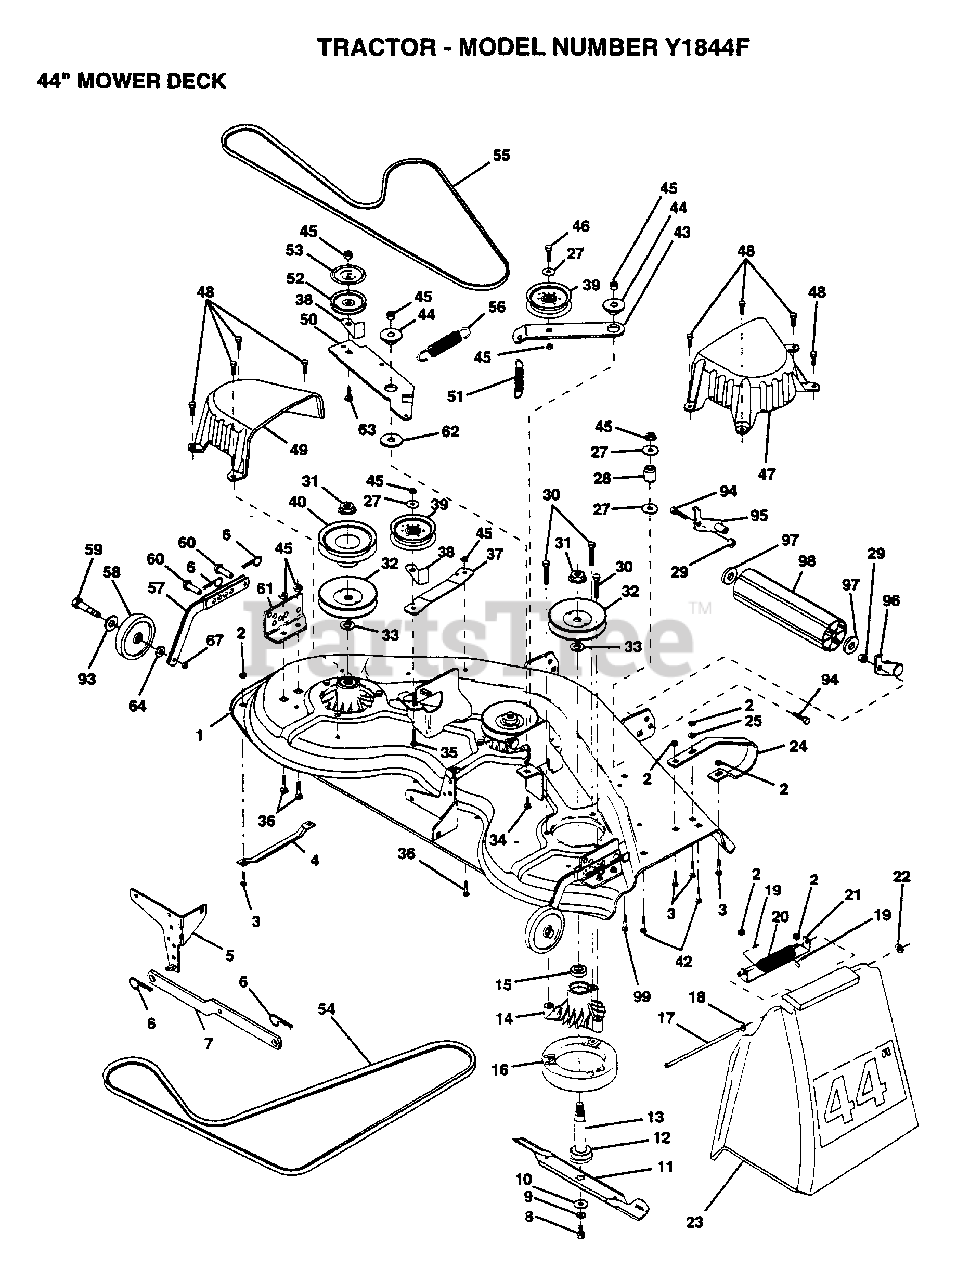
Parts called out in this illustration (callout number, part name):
1	"DECK ASM WELD44"""
4	RUNNER-LH M
5	BRKT.ASM.SW.44/50
8	BLADE BOLT
10	WASHER.HARD.BLADE
11	"BLADE.44"" HIPERF"
12	BEARING.BALL
13	SHAFT.ASM.W/BRNG
14	HOUSING.MAND.44.V
15	BEARING
16	STRIPPER RND MWR
17	ROD-HINGE T
18	WASHER
19	CAP-SLEEVE LT
20	SPRING TORSION
21	BRKT DEFLECTOR
22	NUT PUSH M
23	DEFLECTOR SHIELD
24	RUNNER.RH
24	WASHER M
27	WASHER
29	NUT
33	WASHER
34	BOLT.3/8-14X1.25
35	BOLT
36	BOLT D
37	STIFFENER.ARM.IDL
39	FLAT IDLER PULLEY
40	"PULLEY.DRIVEN.44"""
42	BOLT
43	"ARM.IDLER.SEC.44"""
44	SPACER RETAINER
47	"COVER.MAND.RH.44"""
48	SCREW.1/4-20X5/8
49	COVER.MANDREL.LH
50	"SPRING.SEC.44""VEN"
52	PULLEY.IDLER.VGRO
53	SHIELD.IDLER.44.V
54	V-BELT.PRIM.78.5.
55	BELT-V.88.12.MW
56	SPRING.EXT.DECK.
57	BAR.ASM.GUAGE.WHL
58	WHEEL.GAGE.BLK.PL
59	BOLT M
60	PIN.CLEVIS
61	BRACKET.GUAGE.WHL
62	HARDENED WASHER
63	BOLT.3/8-16X1.50
64	WASHER
67	LOCKNUT
93	WASHER
94	BOLT
97	WASHER
99	BOLT
